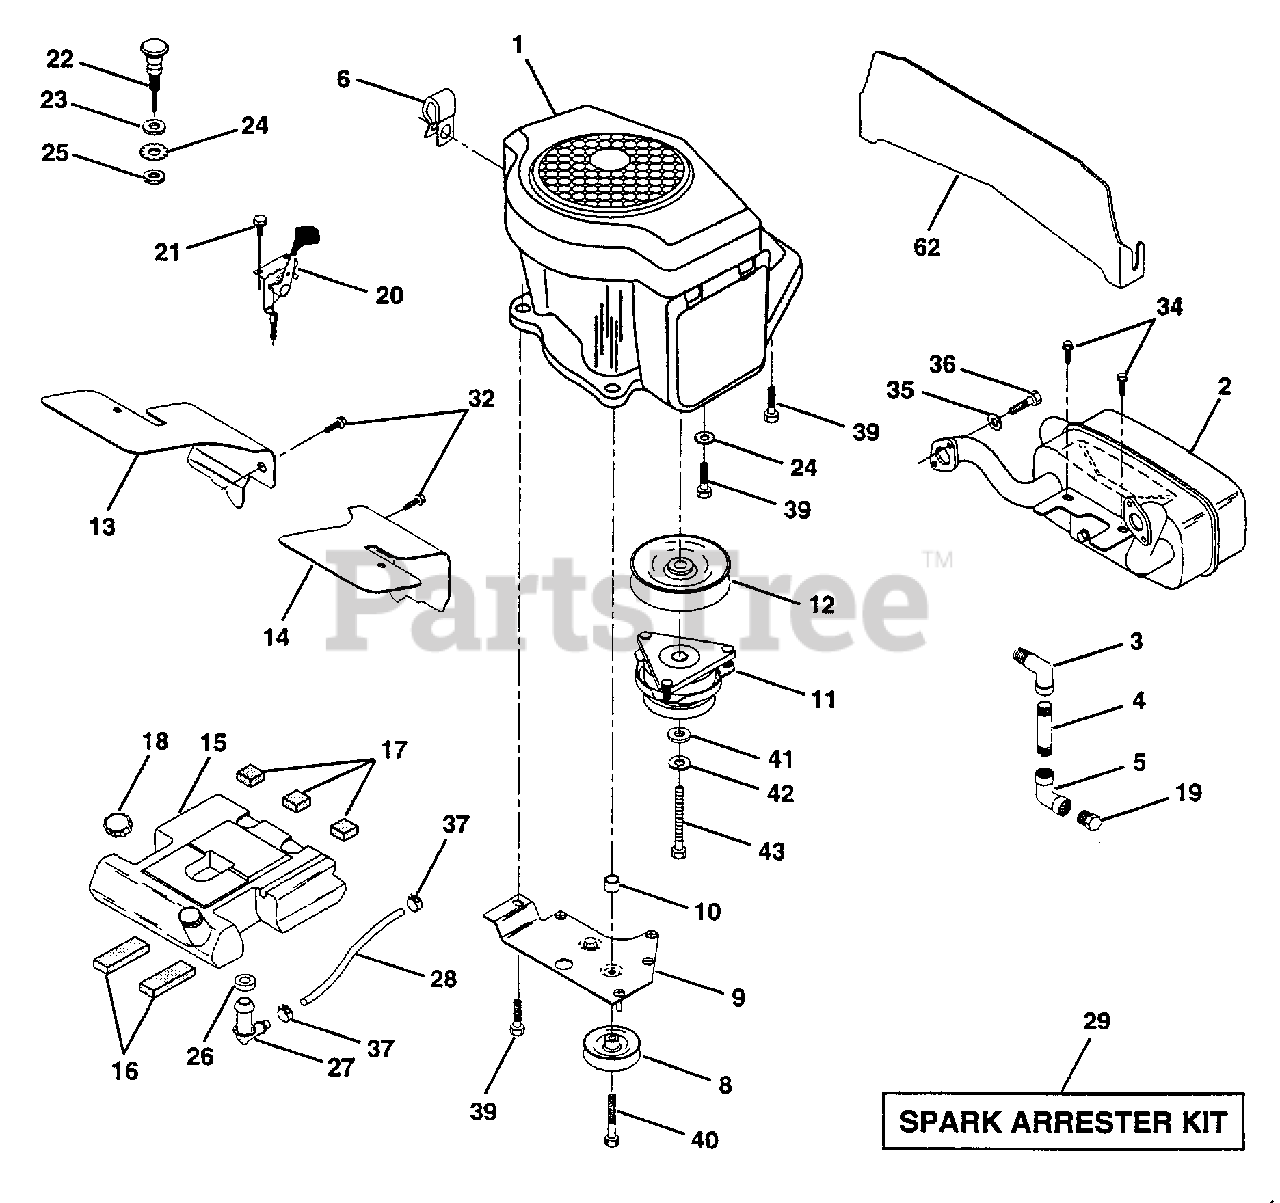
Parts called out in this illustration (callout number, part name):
1	ENGINE KOHLER MODEL
2	MUFFLER.KOH.VCT.
3	STREET ELBOW LT
4	PIPE NIPPLE
5	ELBOW
6	CLAMP.TUBE.DBL.EN
10	BUSHING.
12	PULLEY.ENGINE.VGT
13	BAFFLE.AIR.LH.K
16	PAD IDLER TI
17	PAD-SPACER LT
18	CAP ASM FUEL
19	PLUG T
20	CONTROL THTL 37
21	SCREW LT
22	"CONTROL.CHOKE.51"""
23	WASHER
24	LOCKWASHER
26	BUSHING OUTLET T
27	STEM.TANK.FUEL
29	SPARK ARREST KIT
32	SCREW LT
34	SCREW
35	LOCKWASHER
36	SCREW
37	HOSE CLAMP
39	SCREW LT
40	SCREW.3/8-16X3.25
41	WASHER
42	LOCKWASHER
44	SWITCH OIL KOHLER
45	WIRE LEAD KOHLER
62	SHIELD.HEAT.MUF
